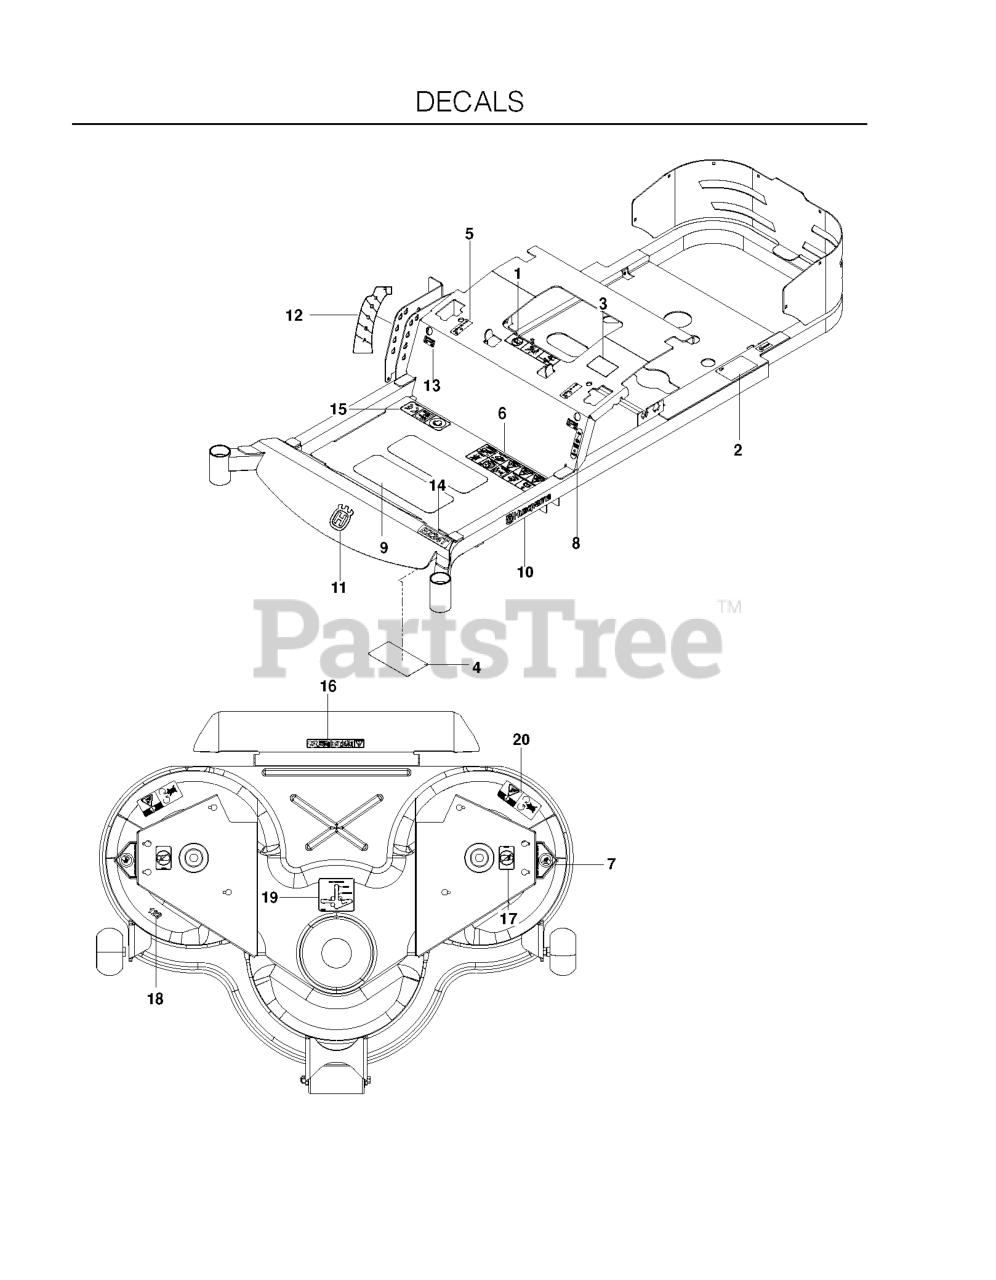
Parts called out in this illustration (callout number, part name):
1	EURO DECAL-BATTERY WARNIN6
2	DECAL, DO NOT TOW
3	DECAL, EXITING MOWER
4	DECAL, SERVICE
5	DECAL, MOTION CONTROL
6	DECAL, SAFETY WARNING
7	DECAL, CPSC
8	DECAL, PARK BRAKE
9	ANTI-SKID PAD
10	RP.DECAL.BADGE.170MM.TEXTLOGO
11	DECAL.AUGER.HUSQ.CROWN.SNOW
12	DECAL, DECK HEIGHT, HUSQ
13	DECAL, F.S.T.
14	DECAL, EZ24T
16	DECAL, DEFLECT WARNING
17	DECAL, NO STEP
18	DECAL, 122
19	DECAL, BELT ROUTING
20	DECAL, BELT DRIVE
